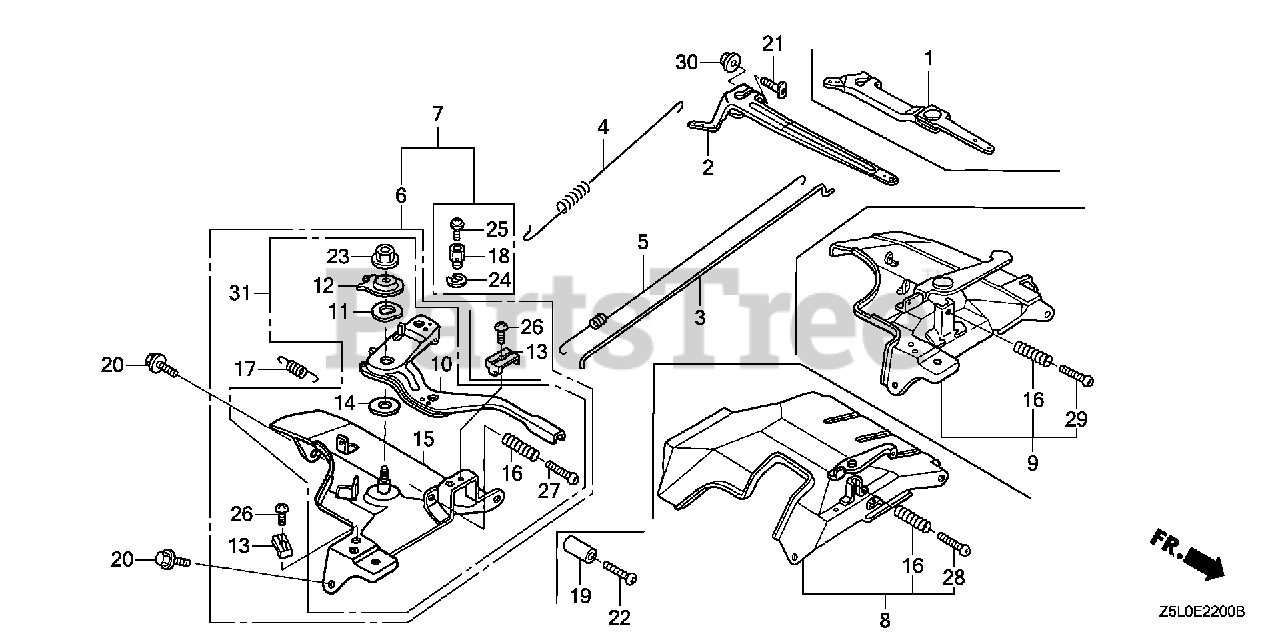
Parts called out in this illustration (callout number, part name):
1	ARM, GOVERNOR
3	ROD, GOVERNOR
4	SPRING, GOVERNOR
5	SPRING, THROTTLE RETURN
8	CONTROL ASSY. (COO)(FOR U.S.A.)
8	CONTROL ASSY.
16	SPRING, CONTROL ADJUSTING Use from Engine SN 2327377.
20	BOLT, FLANGE (6X12) (CT200)
21	BOLT, GOVERNOR ARM
28	SCREW, PAN (5X35)
30	NUT, FLANGE (6MM)
